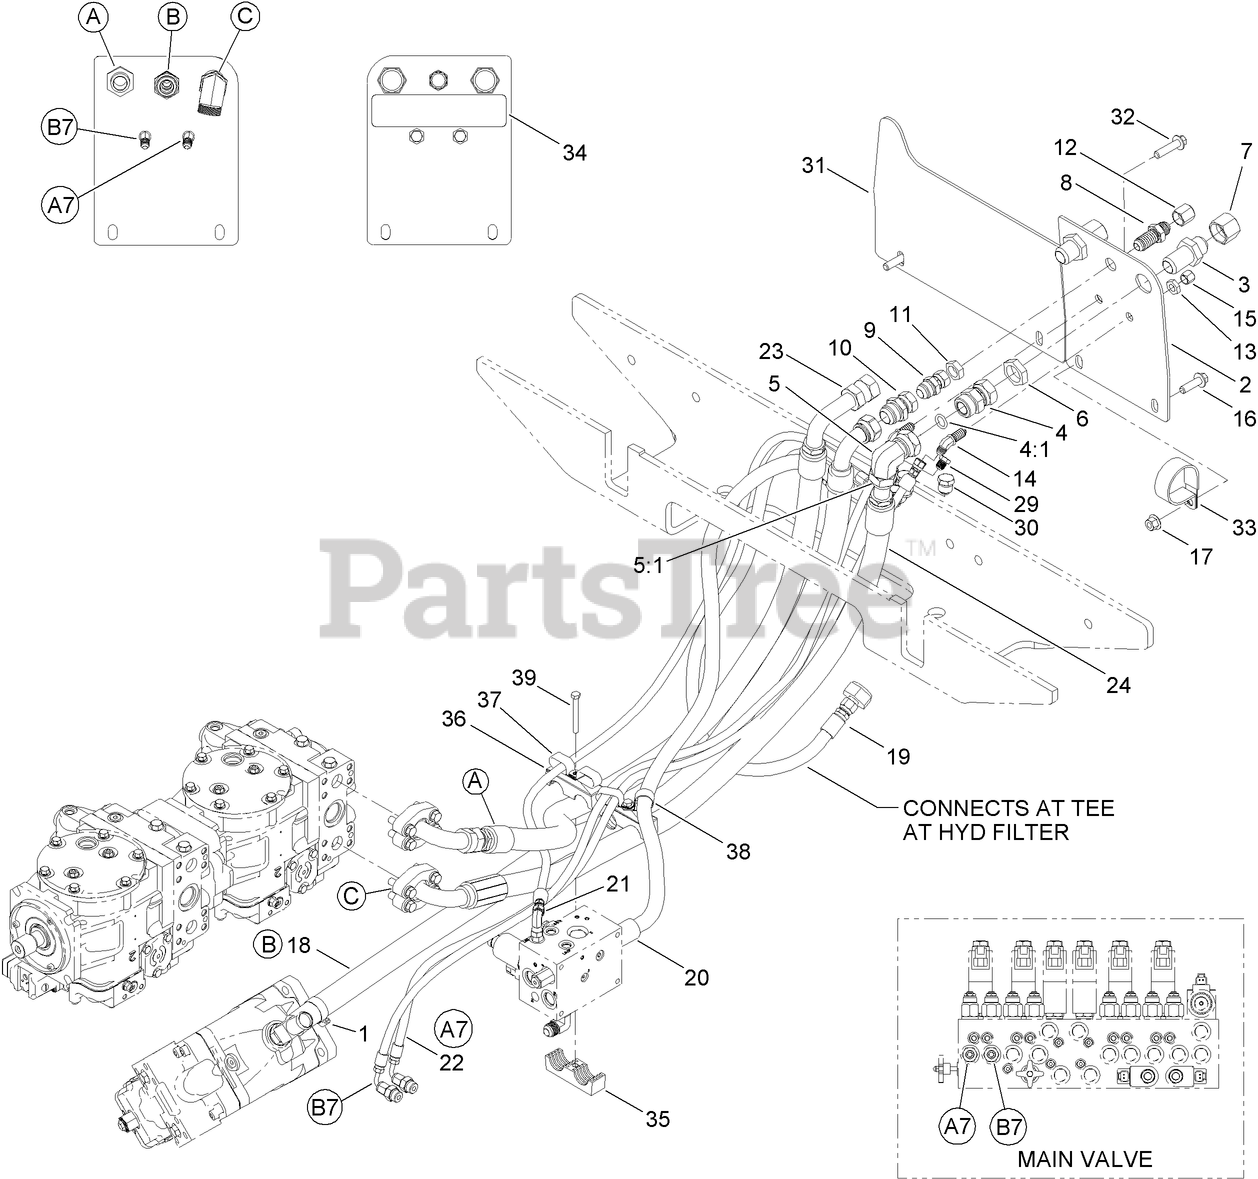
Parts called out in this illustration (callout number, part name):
1	CLAMP-HOSE
2	PLATE-MOUNTING, HYD FITTINGS
3	UNION-BULKHEAD
4	FITTING-STRAIGHT
4:1	O-RING
5	FITTING-SWIVEL, 90 DEG
5:1	O-RING
6	NUT-LOCK, BULKHEAD
8	UNION-BULKHEAD
9	ADAPTER-REDUCER
10	ADAPTER-REDUCER
11	NUT-LOCK, BULKHEAD
12	FITTING-CAP
13	NUT-LOCK, BULKHEAD
14	FITTING-BULKHEAD, ELBOW 45
16	SCREW-HHF
17	NUT-LOCK, HHF
18	HYD RETURN HOSE ASM
19	HYD HOSE ASM, HP
20	HYD HOSE ASM, HP
21	HYD HOSE ASM, HP
22	HYD HOSE ASM, HP
23	HYD HOSE ASM, HP
24	HYD HOSE ASM
31	PLATE-COVER
32	SCREW-HHF
33	CLAMP-R
34	DECAL-ATTACHMENT CONNECTION
35	CLAMP-TWIN
36	PLATE-REATAINER, CLAMP
38	R-CLAMP
39	SCREW-HH
